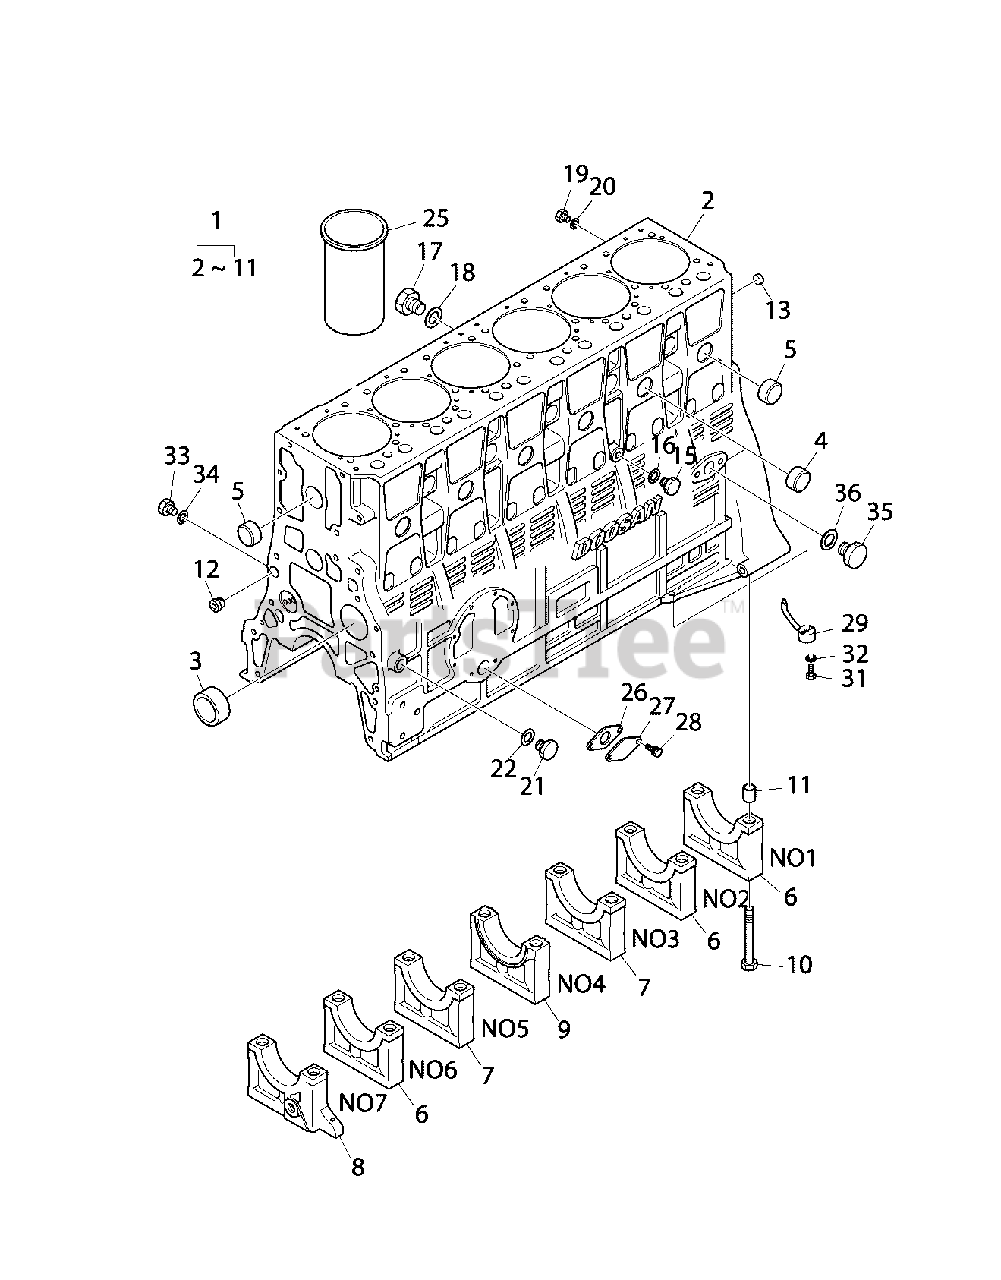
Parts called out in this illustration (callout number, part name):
1	* CYLINDER BLOCK ASSEMBLY
2	* CYLINDER BLOCK
3	* BUSHING, CAMSHAFT
4	* PIN, DOWELL
5	* PLUG, CORE
6	* BEARING CAP 1
7	* BEARING CAP 3
8	* BEARING CAP 7
9	* BEARING CAP 4
10	* BOLT, BEARING CAP
11	* PIN, LOCATING
12	* NOZZLE, OILSPRAY
13	* PLUG, CORE
15	* PLUG SCREW
16	* SEAL, RING
17	* PLUG, SCREW
18	* SEAL, RING
19	* PLUG, SCREW
20	* SEAL, RING
21	* PLUG, SCREW
22	* SEAL, RING
25	* LINER, CYLINDER
26	* GASKET
27	* COVER, BLIND
28	* BOLT
29	* NOZZLE, OILSPRAY
31	* BOLT, HEX
32	* WASHER, SPRING
33	* PLUG, SCREW
34	* SEAL, RING
35	* PLUG, SCREW
36	* SEAL, RING
